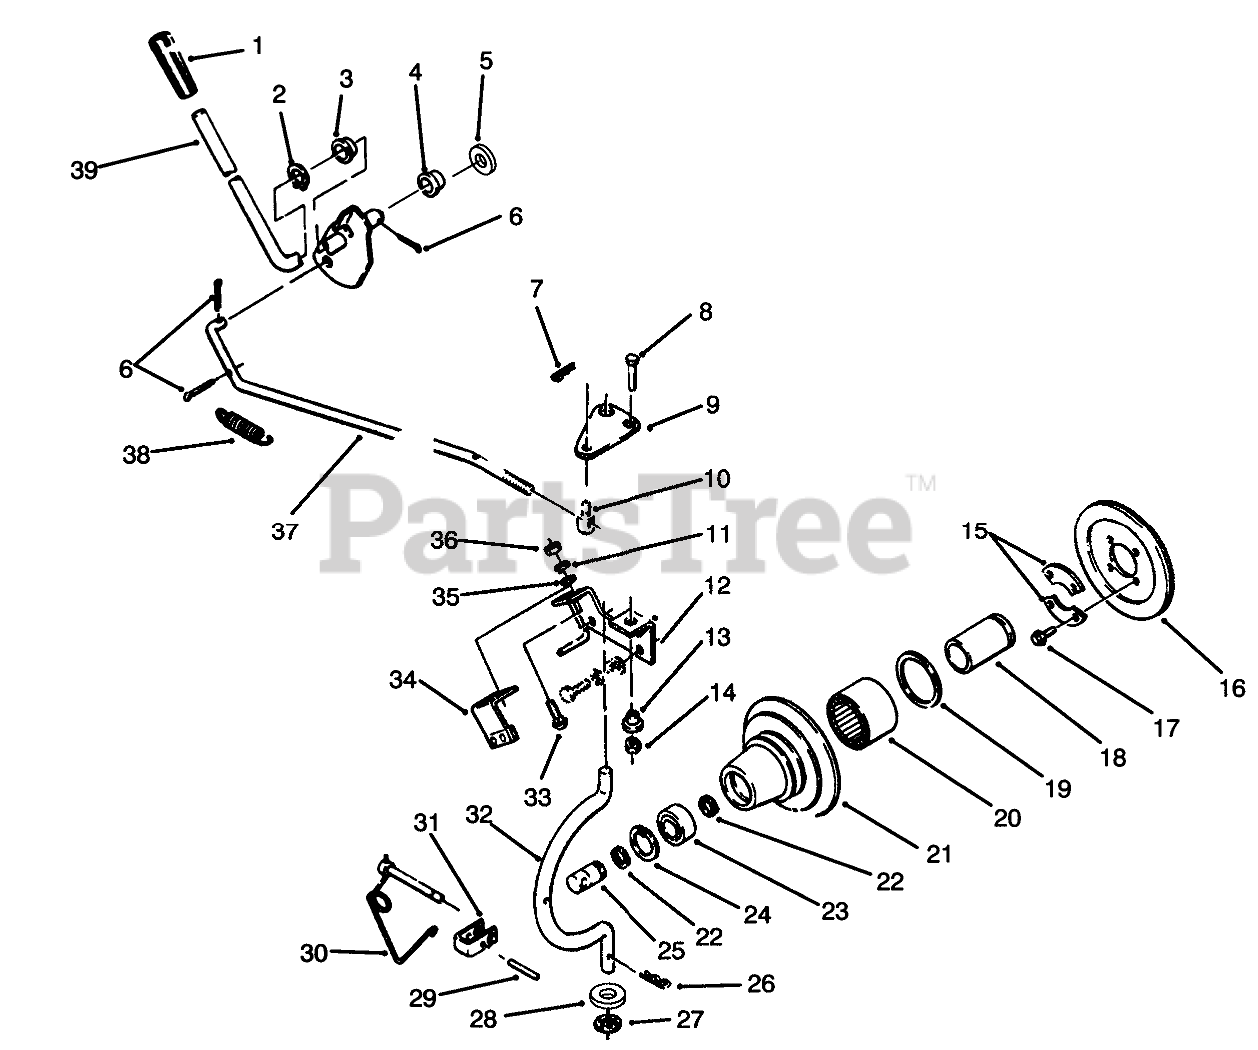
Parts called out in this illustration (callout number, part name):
1	GRIP
2	RING-EXT GRIP
3	BUSHING-NYLINER
4	NYLINER BUSHING
5	SHIM-WASHER
6	PIN-COTTER
7	Hairpin Cotter
8	SCREW-HH
9	PLATE
10	TRUNNION
11	WASHER-LOCK
12	Bracket-Engine
13	SPACER-LIFT LINK
14	NUT-LOCK, NI
15	RETAINER
16	Facing-Clutch
17	H H C S
18	RACE-BEARING
19	SEAL-OIL
20	Seal
21	Housing-Clutch
22	Snap Ring
23	BEARING-BALL
24	RING-RETAINING
25	SHAFT-PTO
26	Hairpin
27	RING-REINFORCED CIRC
28	WASHER-FLAT
30	LOCKING PIN ASM
31	CLEVIS
32	ROD-HOUSING
33	SCREW-CARR
34	ASM-Bracket
35	WASHER-FLAT
36	NUT-JAM
37	ROD-PTO CLUTCH
38	SPRING
39	Lever-Clutch,PTO
